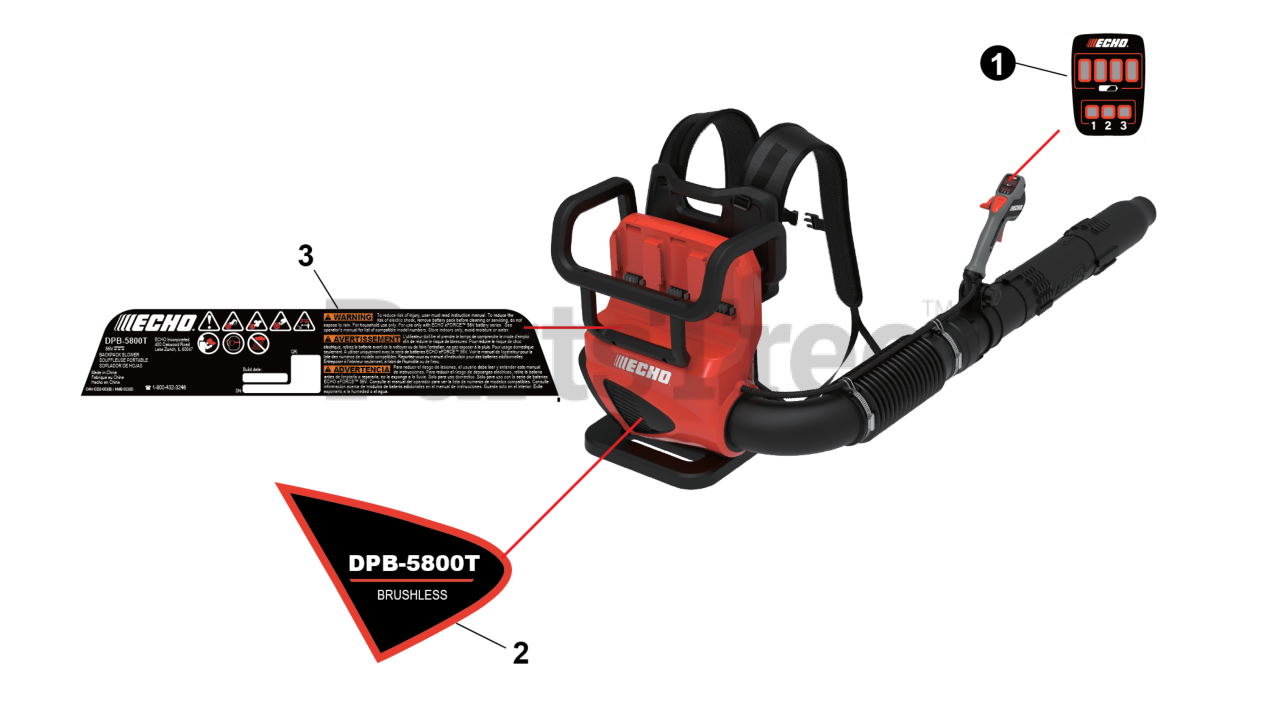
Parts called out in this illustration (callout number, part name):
1	LABEL, LED
2	LABEL, MODEL
3	LABLE,WARNING - CHINA
